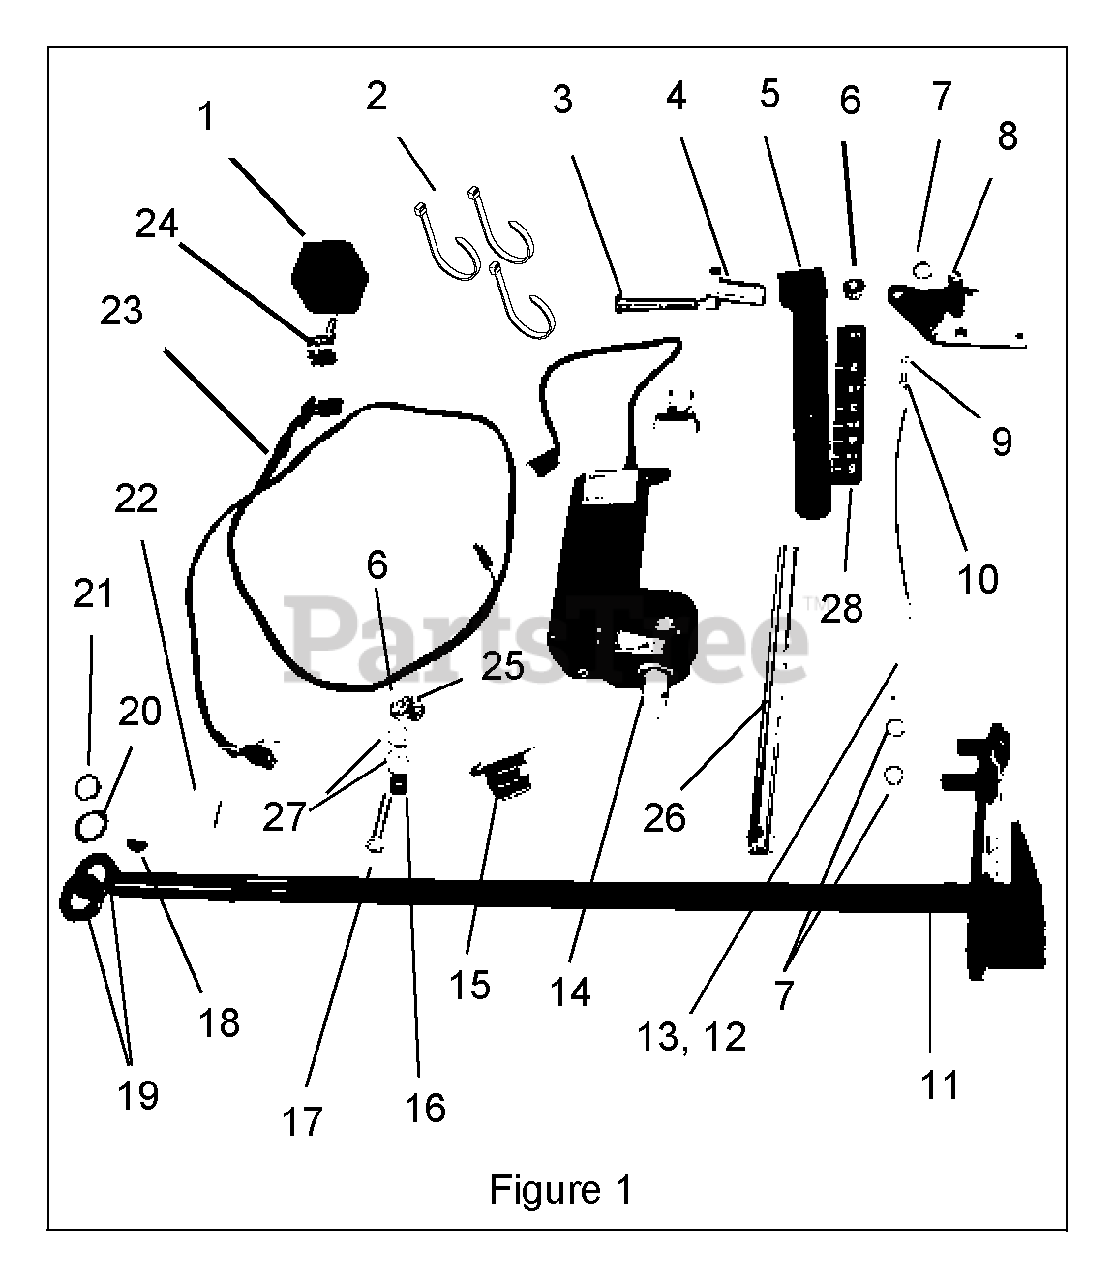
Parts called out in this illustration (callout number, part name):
1	Switch Mounting Bracket
2	Cable Tie, 5-1/2
3	Bolt, Hex 1/2-13 x 3-1/2 Grade 5
4	Bearing, Pedestal
5	Weldment, Cut Height Indicator
6	Nut, 1/2-13 Nylon Lock Flange
7	Ring, Retaining External 5/8 x 3/64
8	Electric Deck Lift Mount Weldment
9	Nut, Locking Top-Flange 1/4-20
10	Bolt, Hex 1/4-20 x 3/4 Grade 5
11	Electric Deck Lift Weldment
12	Cable, Hood
13	Pin, Spring Ball 3/8 OD x 1-1/2
14	Actuator, Linear
15	Clamp, 3/8 Self Adhesive
16	Spacer 33/64 x 3/4 x 5/8
17	Bolt-Hex 1/2-13 x 2-1/2 Grade 5
18	Key, Woodruff 1/4 x 1 Hard #15
19	Washer, Flat-Steel 1-1/16 x 2 x 9/64
20	Washer, Hardened Thrust 1 x 1-35/64 x 1/32
21	Ring, Retaining External 1 x 5/64
22	Pin, Roll 1/4 x 1-1/4 Stainless Steel
23	Harness, Electric Deck Lift
24	Switch, Lift Actuator
25	Screw, Tapping 3/8-16 x 3/4 Hex Washer Head
26	Rod, Cut Height Indicator
27	Washer, Flat Steel 9/16 x 1-3/8 x 7/64
28	Decal, Electric Lift Height of Cut
